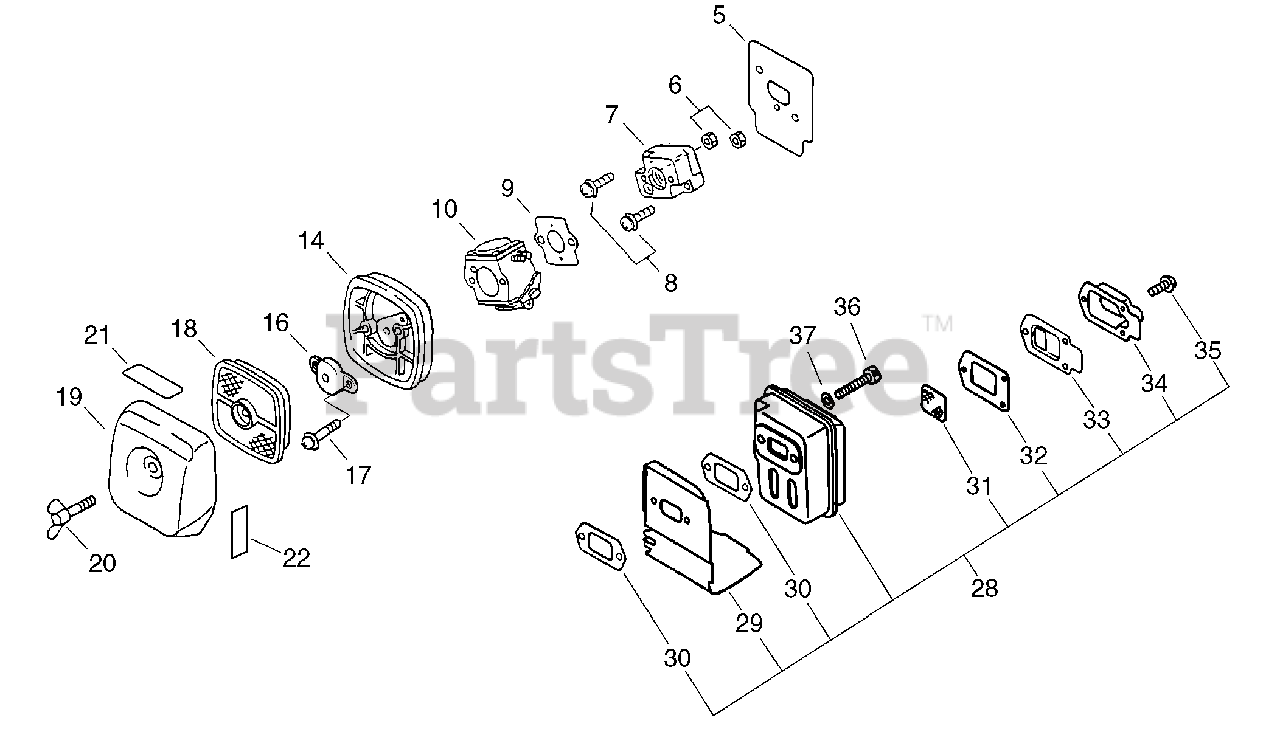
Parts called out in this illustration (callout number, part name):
5	SHIELD, INTAKE
7	INSULATOR, INTAKE
8	SCREW - 5X20
9	GASKET, INTAKE
10	CARBURETOR WT-424C
14	AIR FILTER CASE ASSY
16	PLATE, PREVENT
17	SCREW - 5X65
18	FILTER, AIR - DOUBLE LAYER
19	COVER, AIR FILTER - BLACK
20	THUMBSCREW
21	LABEL - CHOKE
22	LABEL - CHOKE
28	MUFFLER ASSY
29	SHIELD, EXHAUST
30	GASKET, EXHAUST
31	SCREEN, SPARK ARRESTOR
32	GASKET, EXHAUST
33	GASKET, EXHAUST - INNER
34	GUIDE, EXHAUST - OUTER
35	SCREW - 4X10
36	SCREW - 5X55
37	WASHER - 5
